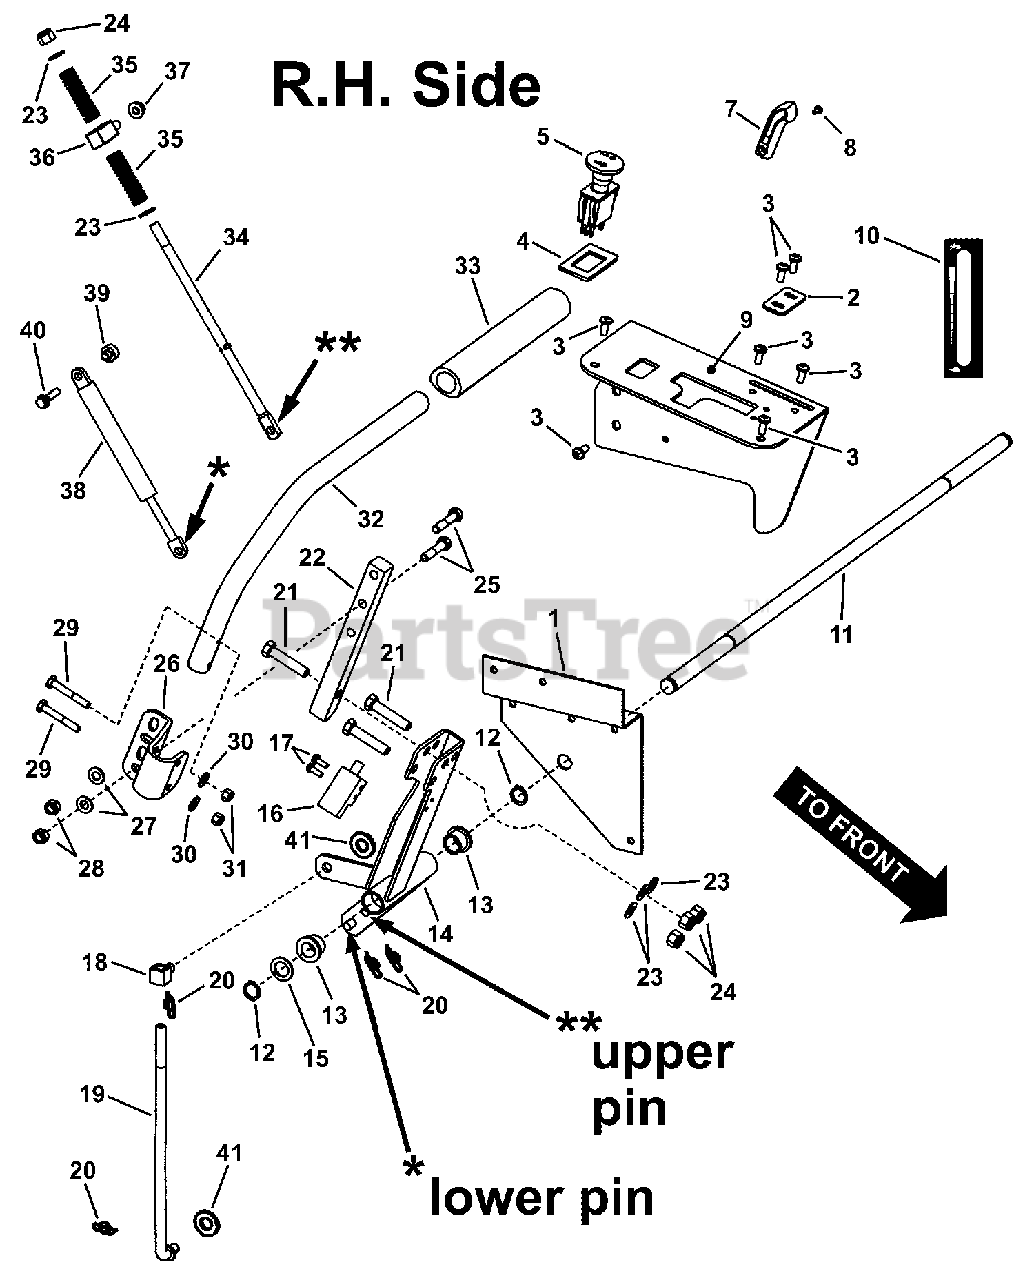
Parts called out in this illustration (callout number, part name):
1	BRACKET, R.H. Tank Support
2	BRACKET, Speed Adjustment
3	SCREW, 1/4-20 x 5/8" Pan Head Self-Tap (Torx)
4	SPACER, PTO Switch
5	SWITCH, PTO E.C. (Delta Part No. 6201-219)
7	LEVER, Throttle Control
8	RIVET, Plastic Snap
9	BRACKET, R.H. Console- Twin Stick
10	DECAL, Throttle/Choke Control
11	SHAFT, Control, Twin Stick
12	RING, 5/8" External Reatining
13	BUSHING, 5/8 x 5/8" Bronze
14	WELDMENT, Twin Stick, RH
15	WASHER, .64 x .99 x .05 Flat
16	SWITCH, Park Brake (NC/NO)
17	SCREW, #10-24 x 1/2" Hex Washer Self-Tap (Torx)
18	SWIVEL, 3/8-16 Internal Thread
19	CONTROL ROD (3/8-16 thread)
20	COTTER-PIN, 1/16" x 1.42" Self-Locking
21	SCREW, 3/8-16 x 1-3/4" Hex Head Cap, GR 5
22	BLOCK, Twin Stick Control
23	WASHER, 3/8" Flat
24	NUT, 3/8-16 Hex Nyloc
25	SCREW, 5/16-18 x 1-1/2" Hex Head Cap, GR 5
26	BRACKET, Handle Adjustment
27	WASHER, .34 x .69 x .08 Flat
28	NUT, 5/16-18 Hex Nyloc
29	SCREW, 1/4-20 x 1-3/4" Hex Head Cap, GR 5
30	WASHER, .28 x .63 x .06 Flat, GR 5
31	NUT, 1/4-20 Hex Nyloc
32	HANDLE, Twin Stick
33	GRIP, Twin Stick
34	RETURN ROD (3/8-16 thread)
35	SPRING, Neutral Return
36	SWIVEL, Shoulder (5/16-18 thread)
37	NUT, 5/16-18 Hex Flange Lock, GR 5
38	DAMPENER, Hydraulic
39	SPACER, Twin Stick
40	BOLT, 1/4-20 x 1-1/8" Hex Flange Lock, GR 5
41	WASHER, 3/8" SAE Flat
